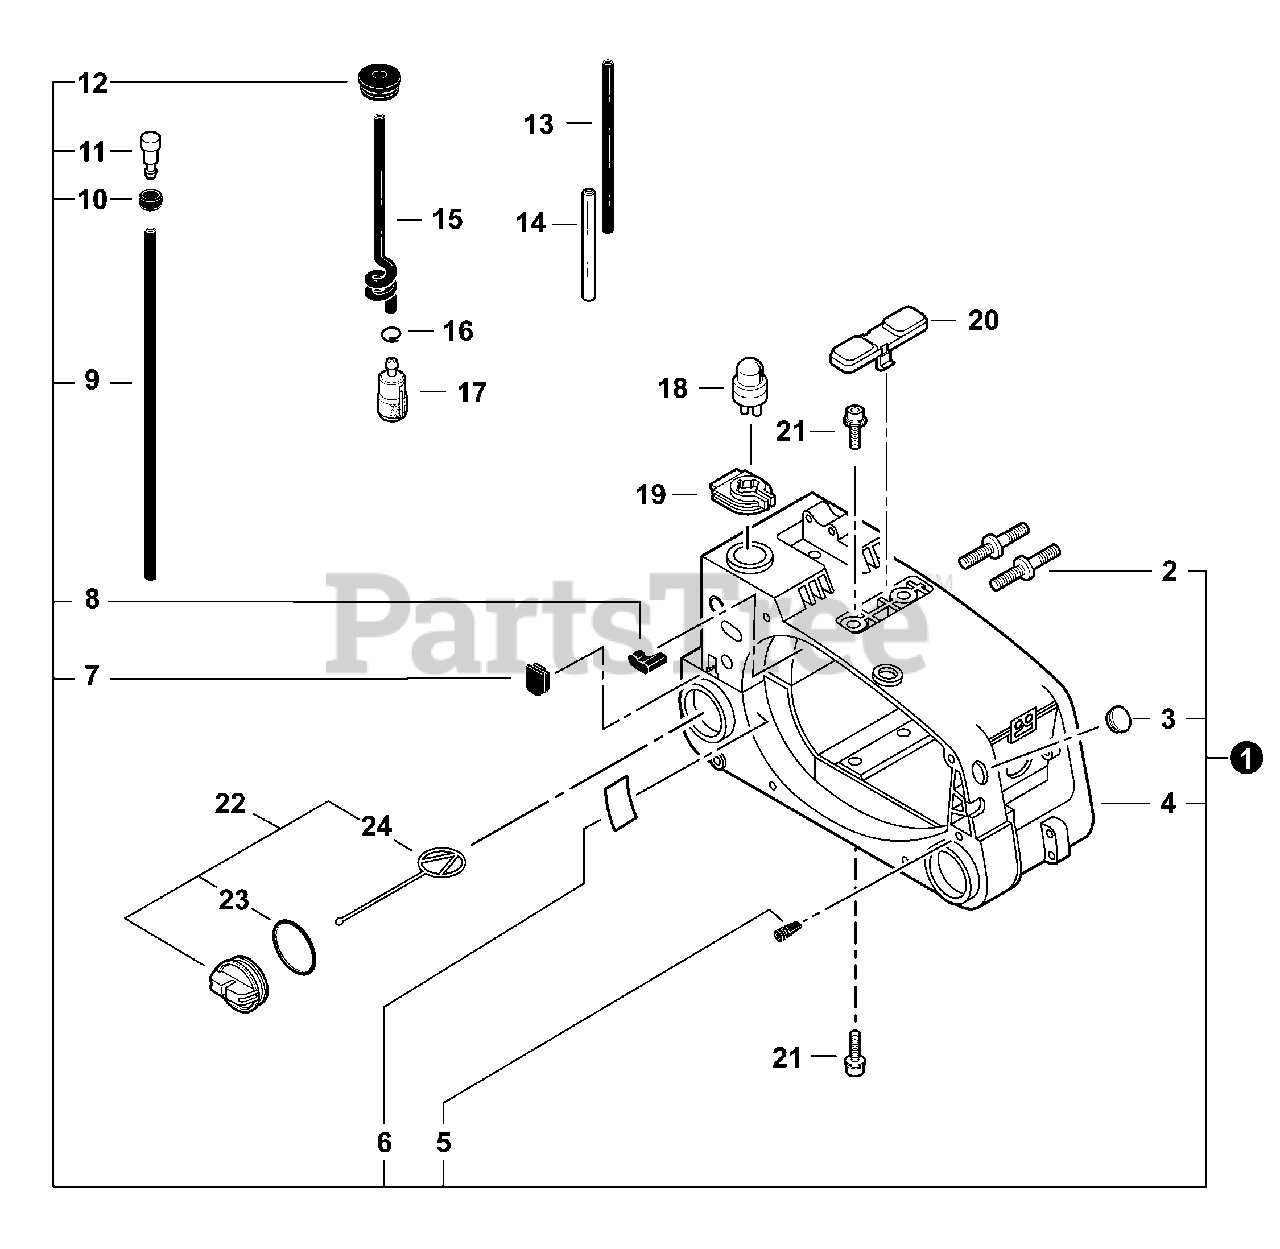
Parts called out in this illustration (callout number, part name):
1	COVER ASSY, ENGINE
2	BOLT, STUD 6
4	COVER, ENGINE
5	VENT ASSY
6	SHIELD, HEAT
9	PIPE, FUEL 3×5×150L BLACK
10	HOLDER, VENT
11	VENT ASSY
12	GROMMET, FUEL
13	PIPE, FUEL 3×5×70 BLACK
14	PIPE, FUEL 2×4×42 CLEAR
15	PIPE, FUEL 3×6×160
16	CLIP 6.5MM
17	FILTER, FUEL
18	BULB, PURGE
19	BRACKET, BULB
20	COVER, TOP
21	BOLT 5×16
22	CAP ASSY, FUEL - ORANGE
24	CONNECTOR, CAP L= 60mm
